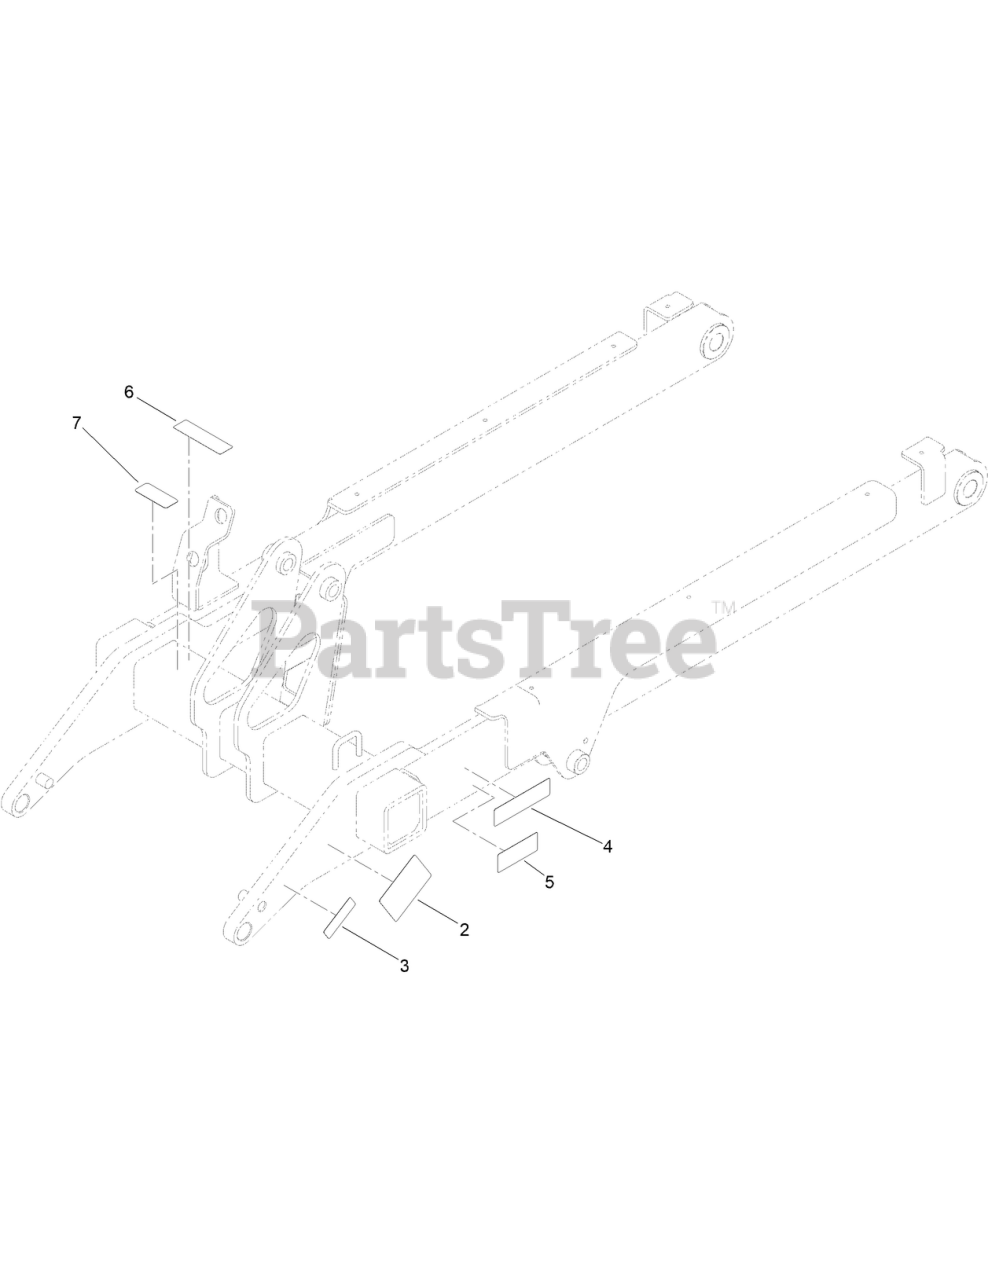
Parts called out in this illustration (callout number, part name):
2	DECAL - WARNING, BUCKET
3	DECAL-WARNING, PINCH POINT
4	DECAL-WARNING, CRUSHING
5	DECAL-WARNING, BYSTANDERS
6	DECAL-CAUTION
7	DECAL-WARNING, HYD PRESSURE
